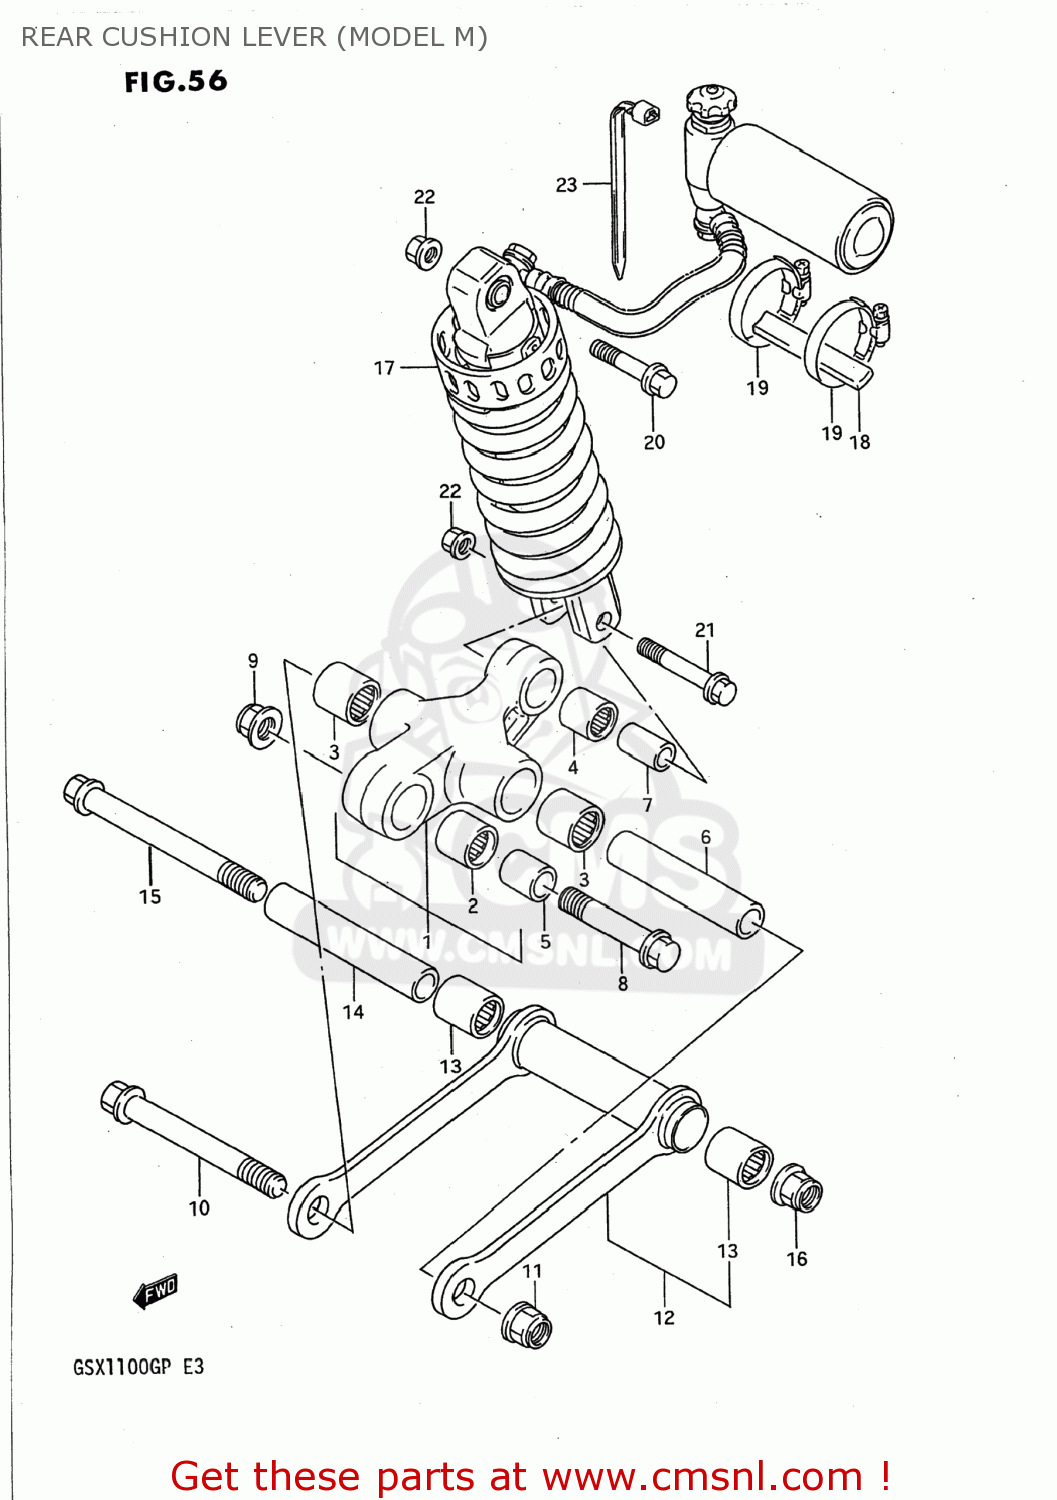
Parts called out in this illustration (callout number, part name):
1	LEVER SET,RR CUSHION
2	BEARING(20X27X32)
3	BEARING(20X27X23.5)
4	BEARING(17X24X26)
5	SPACER(14X20X34)
6	SPACER(14X20X99)
7	SPACER,REAR CUSHION LEVER
8	BOLT(14X66)
9	NUT 14MM
10	BOLT(14X129)
11	NUT 14MM
12	ROD SET,REAR CUSHION,LEFT
13	BEARING(20X27X23.5)
14	SPACER (14X20X129)
15	BOLT(14X159)
16	NUT 14MM
17	ABSORBER ASSEMBLY,REAR SHOCK
18	CUSHION, RESERVOIR TANK
19	CLAMP
20	BOLT(10X50)
21	BOLT(10X60)
22	NUT 10MM
23	CLAMP(L:165)
